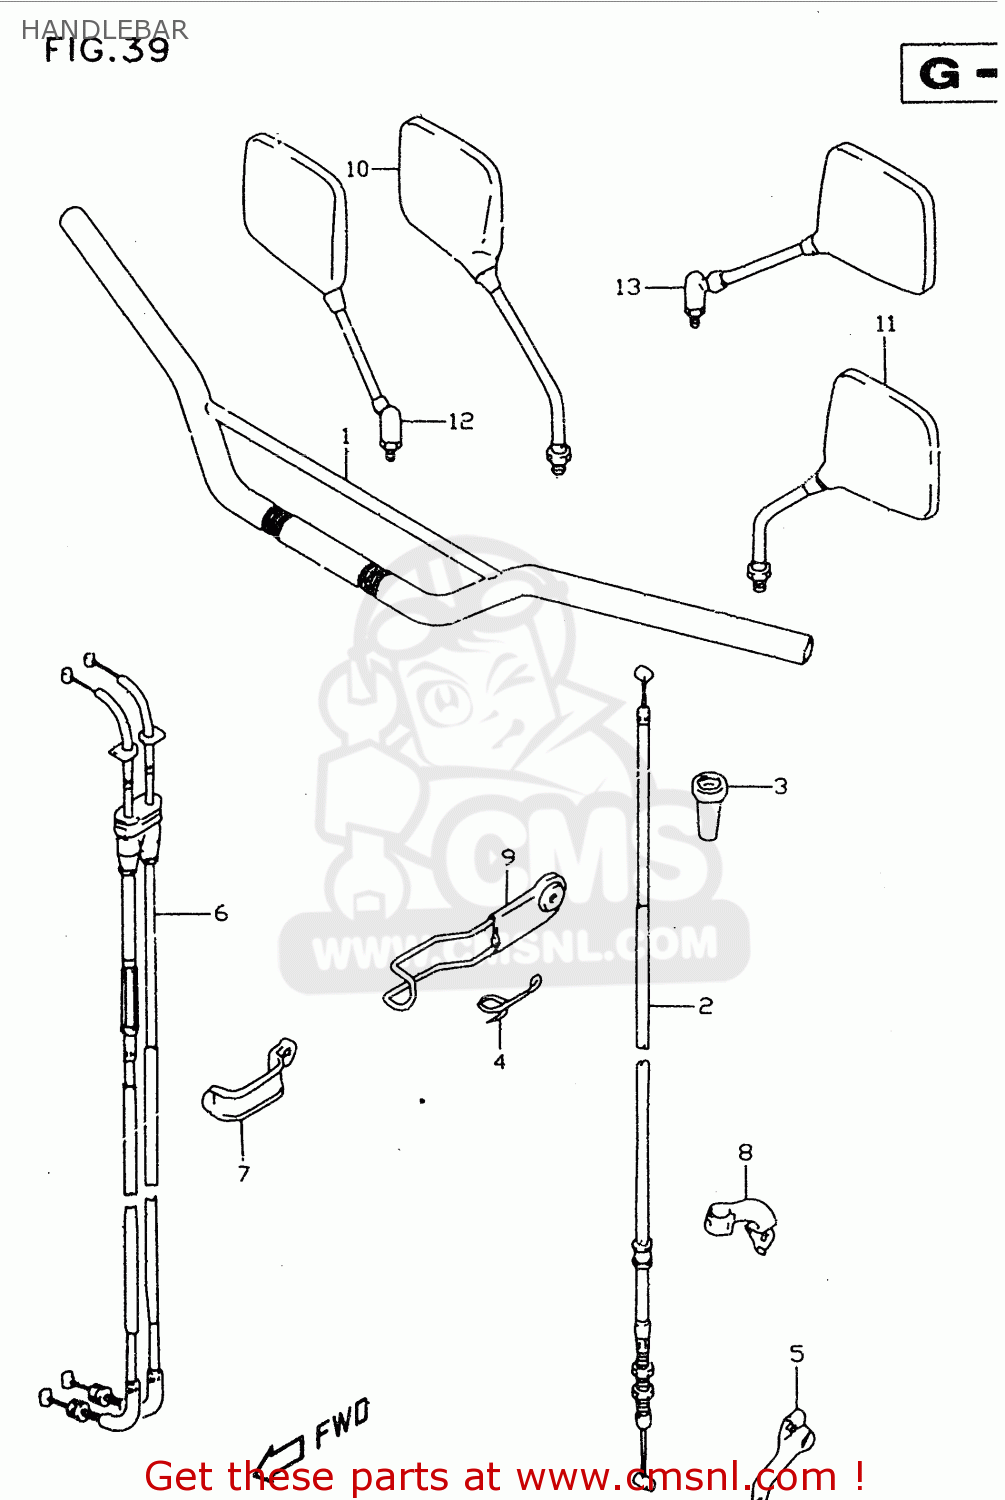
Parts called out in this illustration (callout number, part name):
1	HANDLEBAR
2	CABLE ASSY,CLUTCH
3	BOOT,CLUTCH CABLE
4	GUIDE,CLUTCH CABLE
5	STOPPER,CLUTCH CABLE
6	CABLE ASSY,THROTTLE
7	CLAMP
8	CLAMP,CLUTCH CABLE
9	GUIDE,CLUTCH CABLE
10	MIRROR ASSEMBLY,RIGHT
11	MIRROR ASSEMBLY,LEFT
12	MIRROR ASSY,R.
13	MIRROR ASSY,L.
